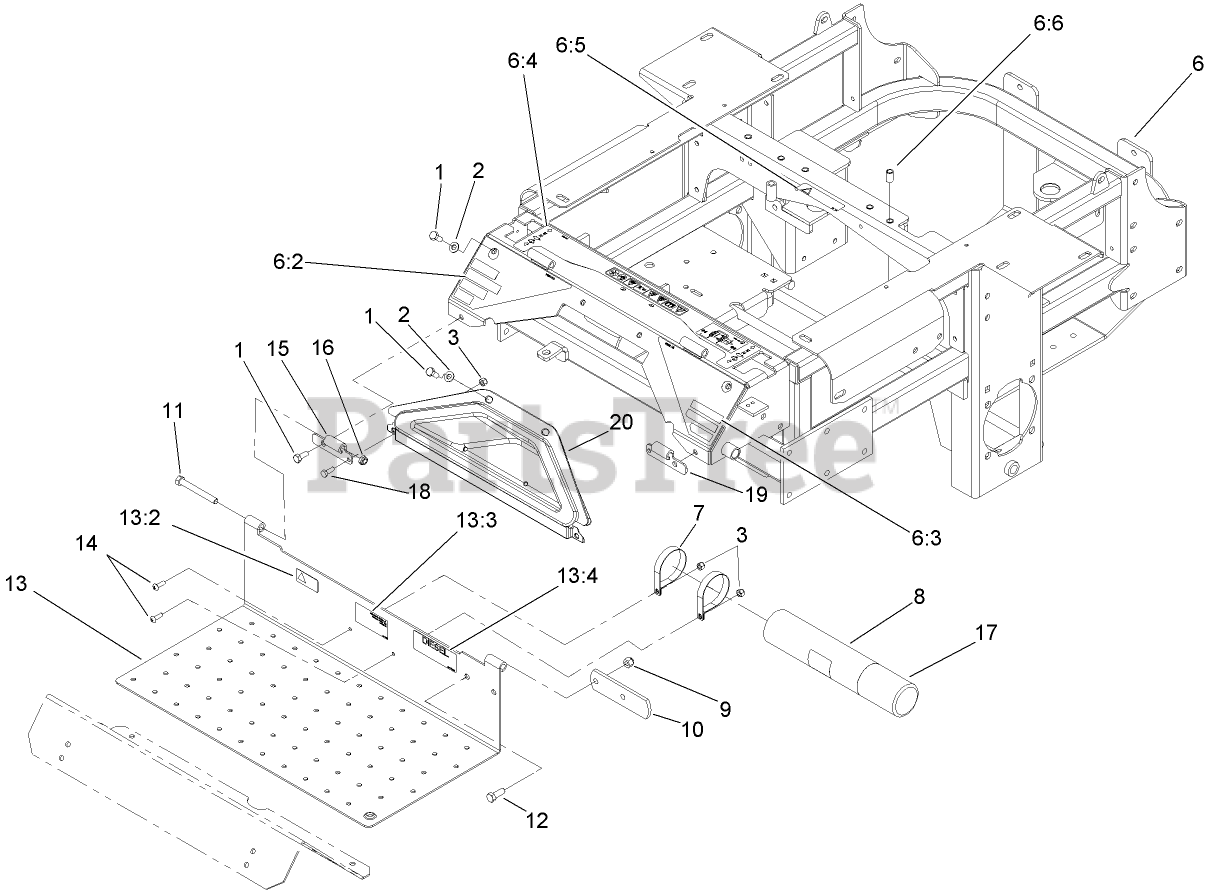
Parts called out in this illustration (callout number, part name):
1	SCREW-HH
2	WASHER-FLAT
3	NUT-LOCK, NI
6	TRACTION FRAME ASM
6:2	Decal-Warning
6:3	Decal-Danger
6:4	DECAL-CONSOLE, TOP
6:5	DECAL-COVER, MISSING
6:6	INSERT-THREADED
7	R-Clamp
8	TUBE-MANUAL
9	NUT-LOCK, NI
10	STOP-BRAKE, PARK
11	SCREW-HH
12	SCREW-HH
13	FLOOR PAN ASM
13:2	DECAL-PROTECTION, EAR
13:3	Decal-Location, Manual
13:4	DECAL-DIESEL
14	SCREW-PRH
15	Hinge-Floorpan, LH
16	NUT-LOCK, NI
17	CAP-HOUSING
18	SCREW-HH
19	Hinge-Floorpan, RH
20	Pocket
